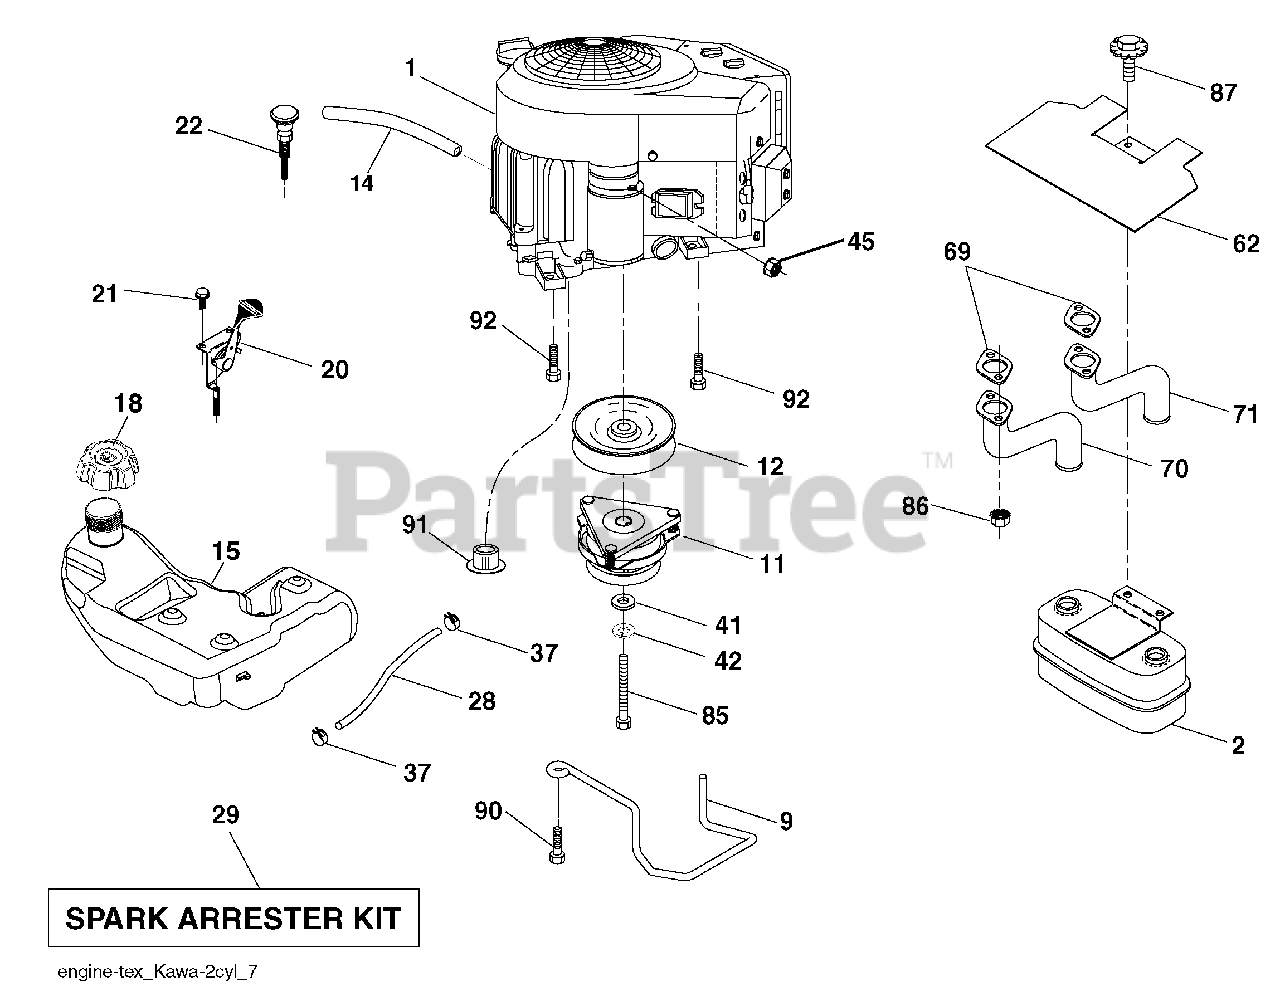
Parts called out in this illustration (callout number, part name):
9	Keeper Belt Engine
11	Clutch Electric
12	Pulley Engine
14	Tube Drain Oil Easy
15	Tank Fuel 4.0
18	Cap Asm
20	Control Throttle
21	Screw #10 x 0.750 BOS Thread
22	Control Choke
28	Fuel Line
29	Spark Arrester Kit
37	Clamp Hose
41	Washer 1-1/2 OD x 15/32 ID x .250
42	Washer Lock 7/16
45	Nut Keps Hex 1/4-20 unc
62	Shield Heat Muffler
70	Tube Exhaust LH
71	Tube Exhaust RH
85	Bolt Hex 7/16-20 x 3.75 Gr. 5
86	Nut Hex Flange Toplock M8-1.25
87	Bolt 5/16-18 unc x 1 w/Sems
90	Screw 3/8-16 x 1
92	Screw 3/8-16 x 1
